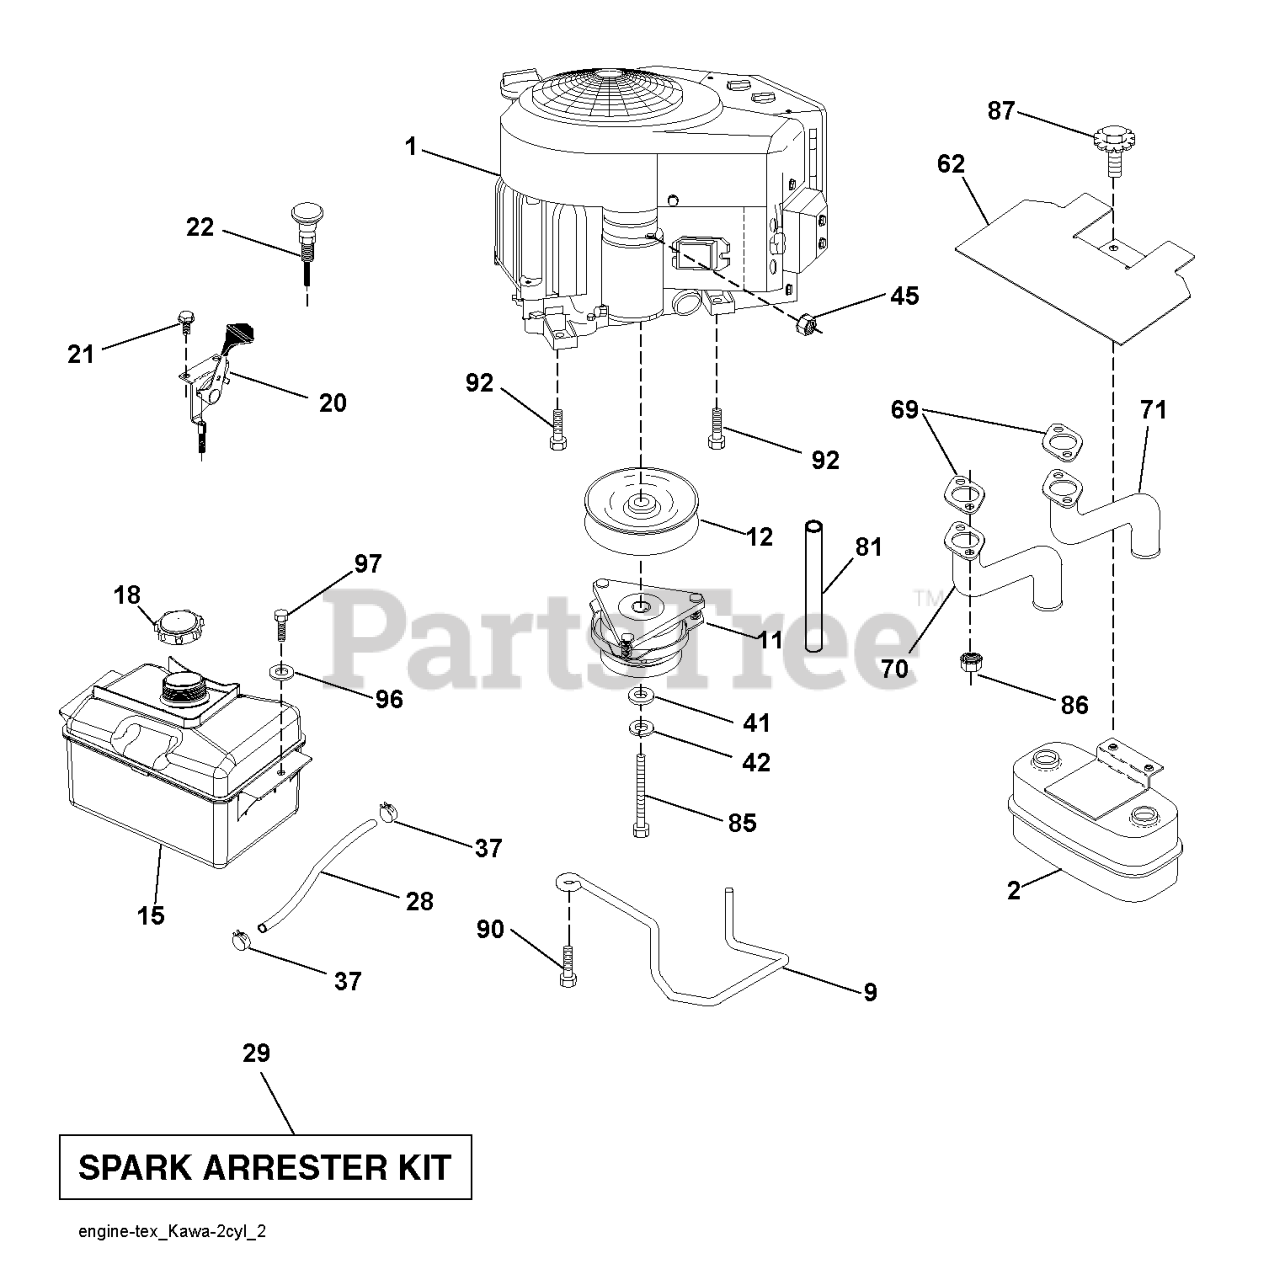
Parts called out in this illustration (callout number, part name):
2	MUFFLER.TWIN.CYL.LOW.TONE
9	KEEPER.BELT.ENGINE.4.2
11	RB.CLUTCH.OGURA.4.4.PD
12	PULLEY.ENGINE.TUFFTORQ
15	RP TANK FUEL FRT 1.5 GAL
18	CAP.FUEL.2.25"VENTED"
20	THROTTLE CABLE
21	SCREW.#10 X 0.750.BOS
22	CONTROL, CHOKE
28	LINE.FUEL.20
29	KIT.SPARK ARRESTOR 794945 B&S
37	HOSE CLAMP
42	LOCKWASHER
45	NUT
62	RP SHIELD HEAT MUFFLER
70	EXHAUST.TUBE.LH.KAWASAKI.
71	EXHAUST.TUBE.RH.KAWASAKI.
81	TUBE, DRAIN OIL ASM.
85	BOLT HEX 7/16-20X4-1/4"
86	NUT.HEX.FLANGE.TOPLOCK
87	BOLT.5/16-18UNCX3/4 W/SEMS.BLK
90	SCREW 3/8-16X1
92	SCREW 3/8-16X1
96	WASHER
97	SCREW HEXWSHR 1/4-20X3/4
